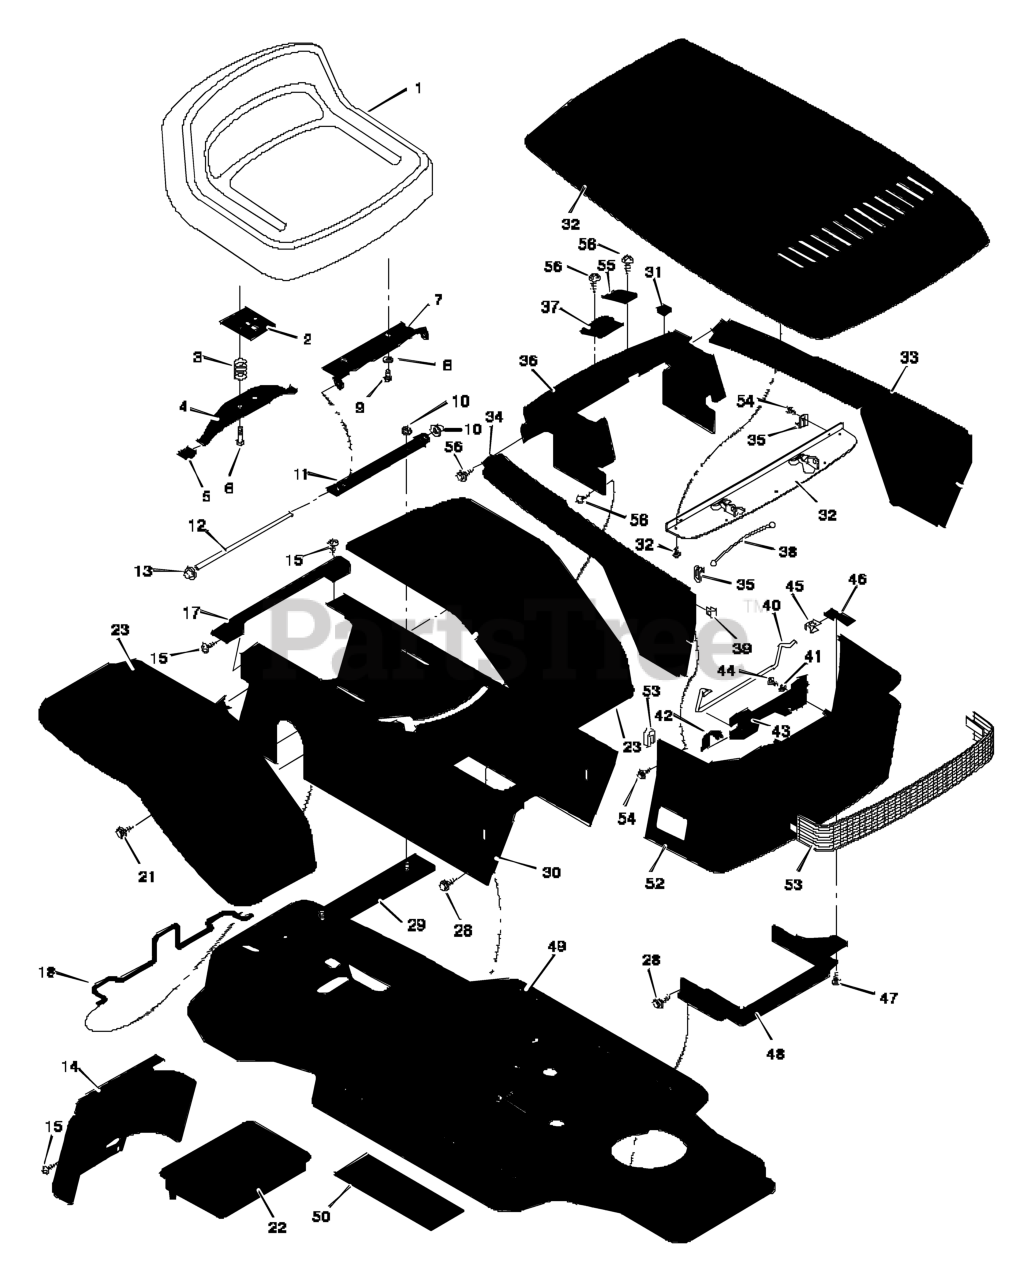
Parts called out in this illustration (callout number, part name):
2	Plate Assembly, Switch
3	Spring, Compression
4	Spring, Seat
5	Glide, Spring
6	Bolt, Shoulder
7	Support, Seat
8	Lockwasher
9	Bolt, Hex
10	Locknut, Flange
11	Bracket, Pivot
12	Rod, Pivot
13	Cap, Push On
14	Cap, Console
15	Screw
17	Fender, Apron
18	Clamp, Battery
22	Tray, Battery
29	Channel Assembly
30	Console Assembly
31	Trim, Edge
32	Hood Assembly
33	Panel, Left
34	Panel, Right
35	Clip, Cable
36	Dash Assembly
37	Bearing, Steering
39	U-Fastener
40	Rod, Hinge
42	Spring, Hood
43	Bracket, Hood Mount
45	Nut, Speed
46	Shield, Heat
48	Support, Grille
49	Frame Assembly
53	Lens
55	Bearing
